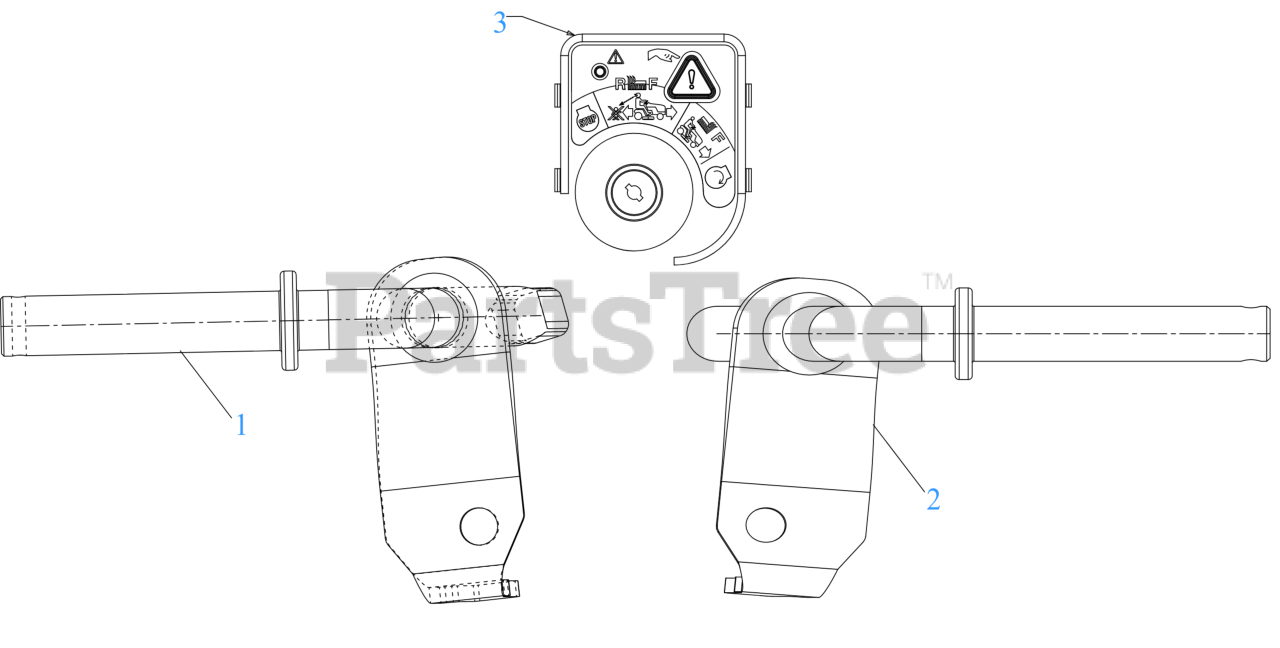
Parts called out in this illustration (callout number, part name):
1	AXLE ASSEMBLY, (RH)
2	FRONT AXLE ASSEMBLY(LH)
3	IGNITION MODULE SWITCH RMC (MAN PTO BLK)
